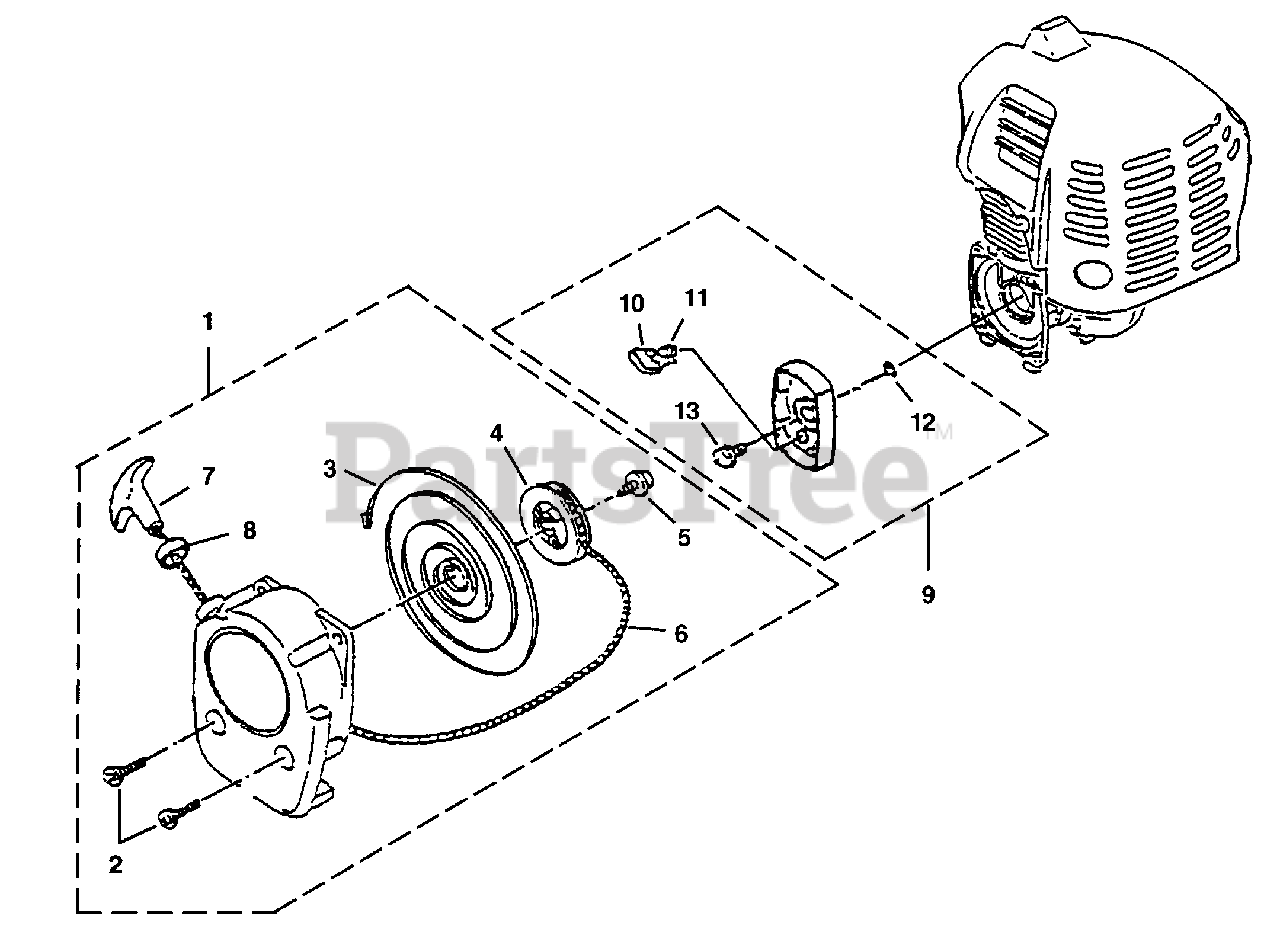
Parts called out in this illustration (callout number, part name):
1	STARTER COMPLETE
2	SCREW-Socket Hd (M5 x 18 W SW)
5	SCREW-Set (M5 x 30)
6	ROPE-Starter
8	DAMPER-Grip
9	STARTER CUP ASSEMBLY
11	SPRING-Return
13	BOLT ASSEMBLY (M6 x 14W)
